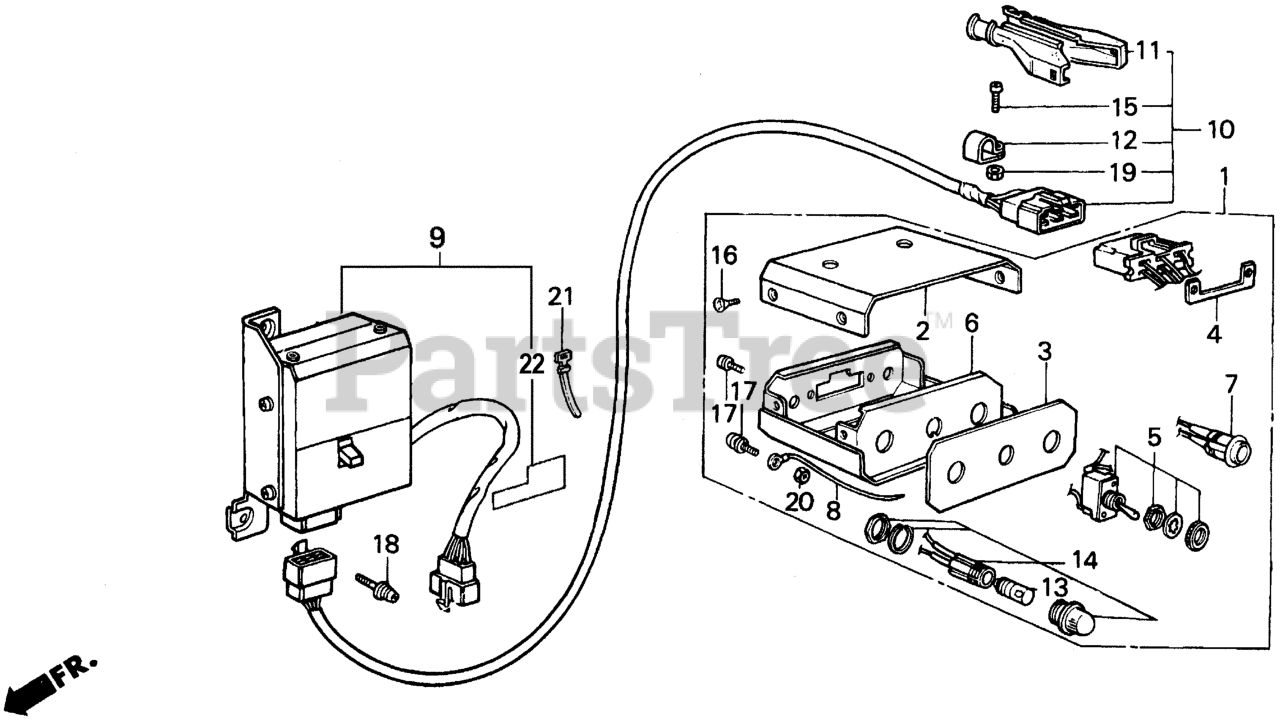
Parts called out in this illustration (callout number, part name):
1	BOX ASSY., SWITCH (NOT AVAILABLE)
2	COVER (UPPER) Use from Frame SN 1001725.
3	PLATE, SWITCH & INDICATOR
4	PLATE, CONNECTOR SETTING
5	SWITCH, TOGGLE
6	CASE, SWITCH *R280* Use from Frame SN 1120560.
7	SWITCH, PUSH
8	WIRE, GROUND
9	BOX ASSY., RELAY
10	CABLE, REMOTE CONTROL (10MM)
11	COVER, CONNECTOR
12	BAND
13	BULB, WEDGE BASE (12V/2W) Use from Frame SN 1001725.
14	SOCKET ASSY., LAMP (GREEN) Use from Frame SN 1001725.
15	SCREW, PAN (3X12)
16	SCREW, FLAT (4X8) Use from Frame SN 1001725.
17	SCREW-WASHER (4X12)
18	SCREW-WASHER (6X25)
19	NUT, HEX. (3MM)
20	NUT, HEX. (4MM)
21	BAND B1, CABLE
22	MARK, REMOTE CONTROL
